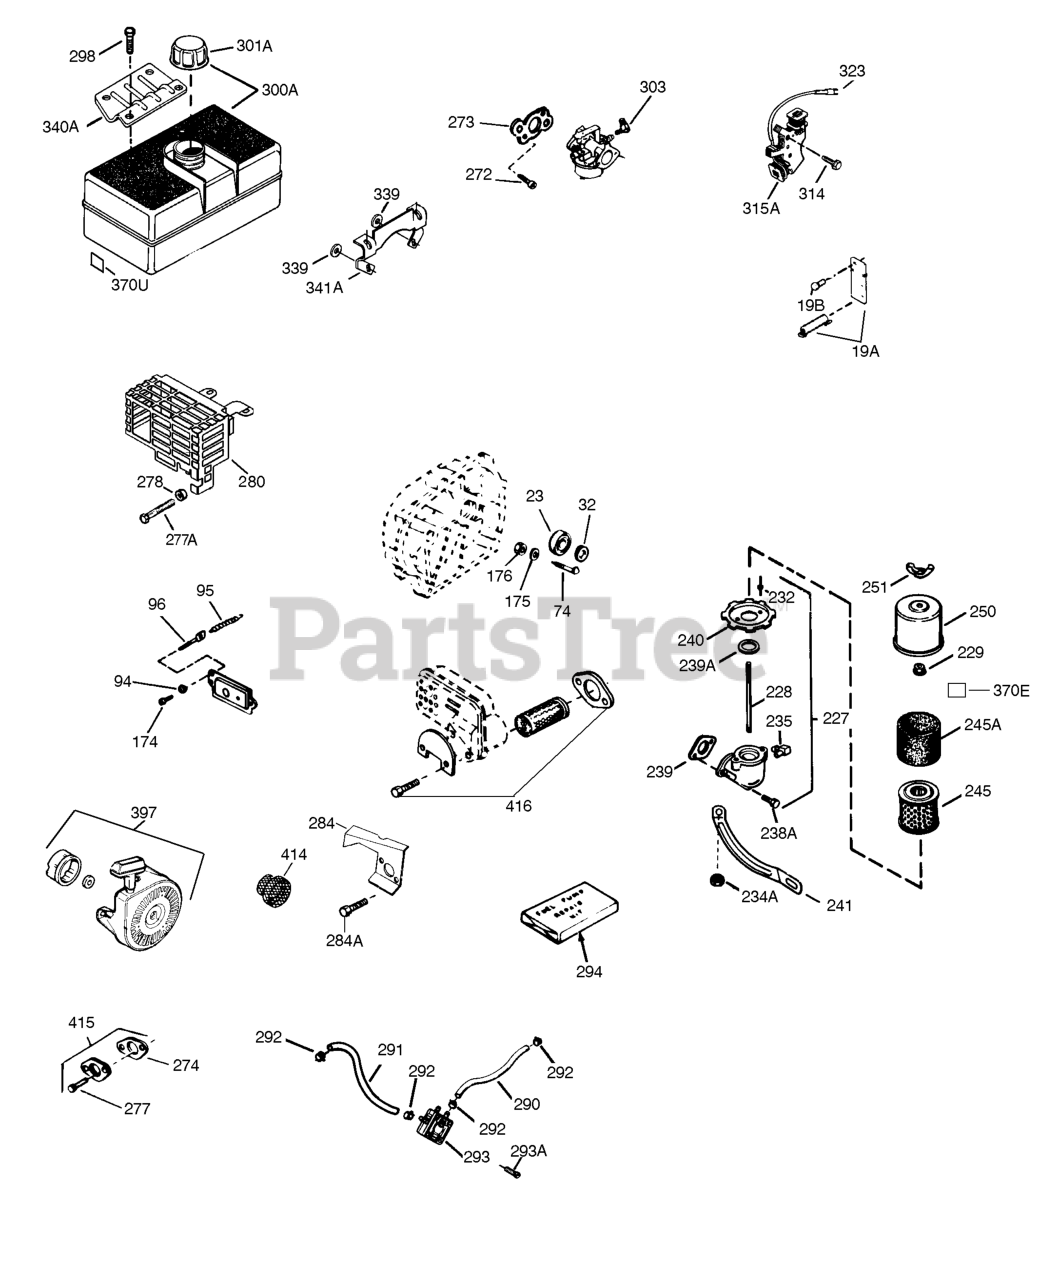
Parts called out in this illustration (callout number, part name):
131A	SCREW
186	GOV LINK
290	FUEL LINE
